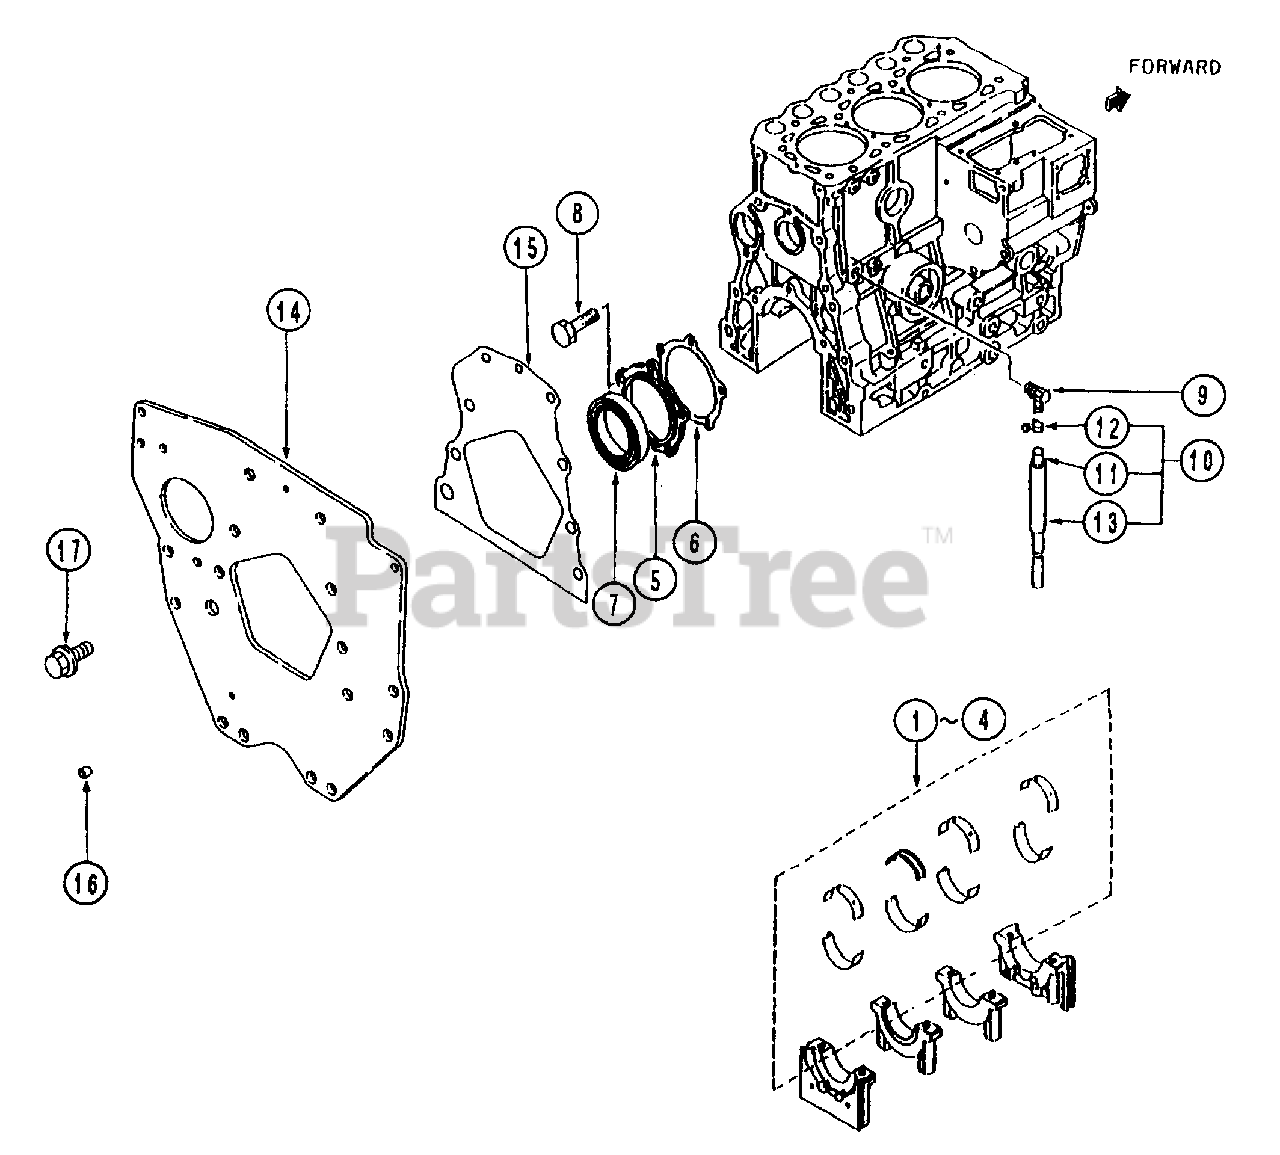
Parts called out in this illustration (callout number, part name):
1	Metal Set STD
2	Metal Set U.S 0.25
3	Metal Set U.S 0.50
4	Metal Set U.S 0.75
5	Case, Oil Seal
6	Gasket, Oil Seal Case
9	Joint, Water Drain
10	Hose Ass'y, Water
14	Plate, Rear
15	Gasket, Rear Plate
17	Bolt, Flange
